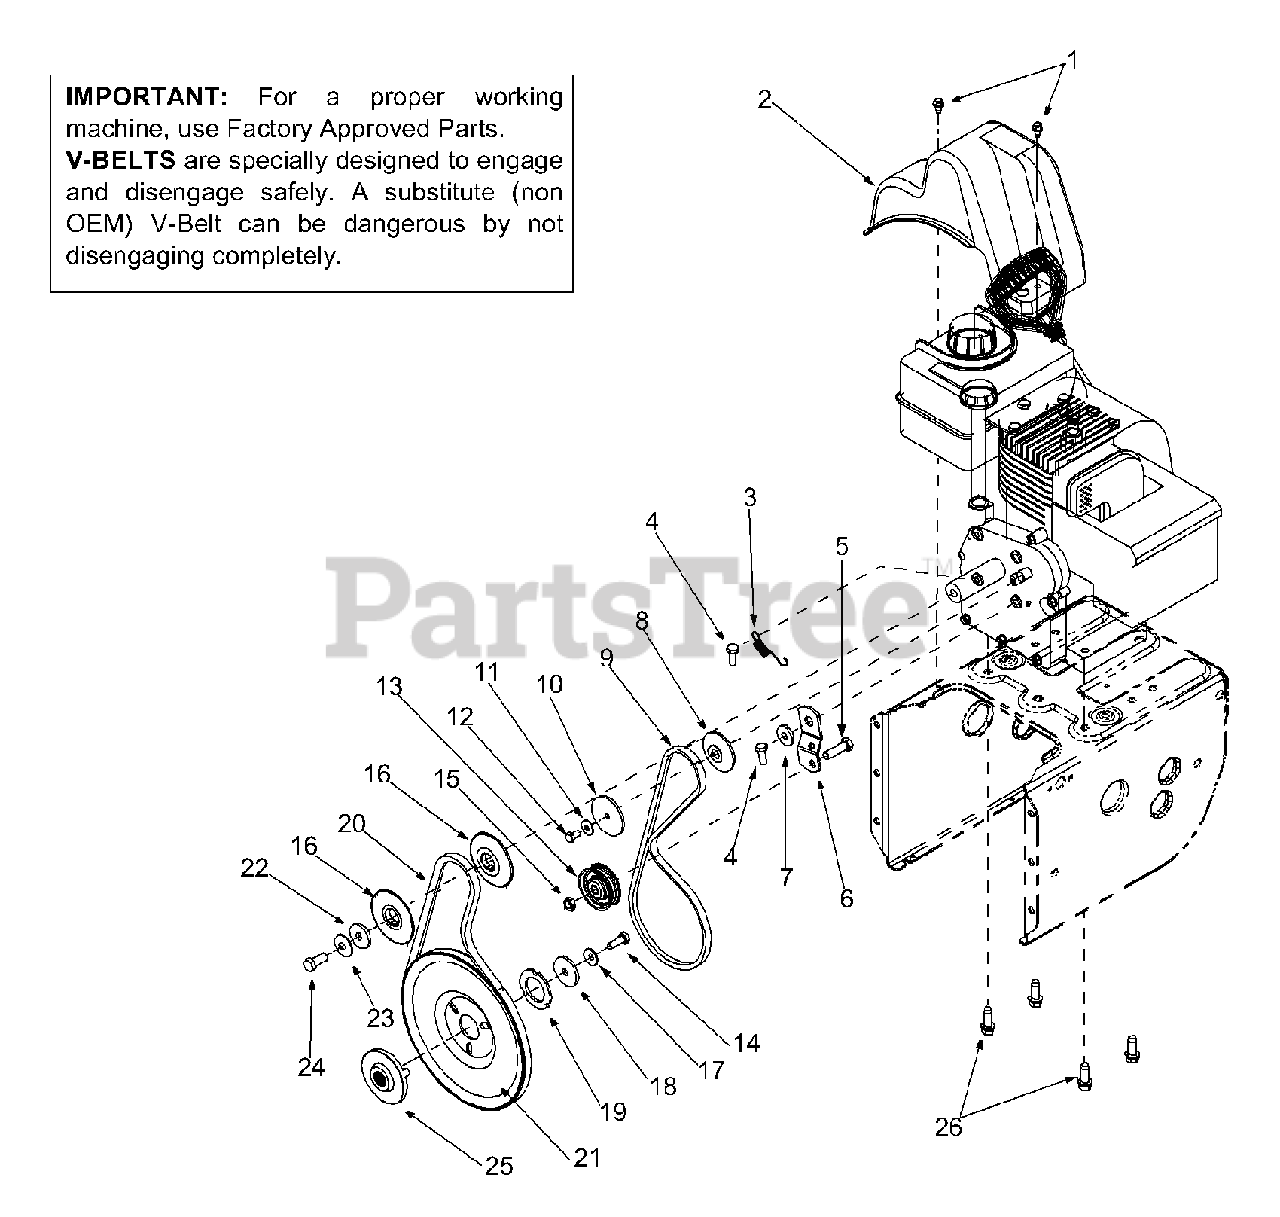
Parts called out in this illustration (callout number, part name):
1	Hex Washer Screw 1/4-20 x.5
2	Belt Cover
3	Extension Spring
4	Hex Screw 5/16-24 x .75
5	Hex Cap Screw 3/8-16 x 1.25
8	Pulley Half
9	V-Belt
10	Pulley Half
11	Bell Washer
12	Hex Cap Screw 1/4-28 x .50
13	Flat Idler
14	Lock Cap Screw 5/16-24
15	Lock Jam Nut 3/8-16
16	Pulley Half
17	Bell Washer
18	Flat Washer
19	Washer
20	Belt
21	Auger Pulley
22	Flat Washer
23	Bell Washer
24	Hex Cap Screw 3/8-24
25	Pulley
26	Hex Washer Screw 3/8-16 x 1.0
